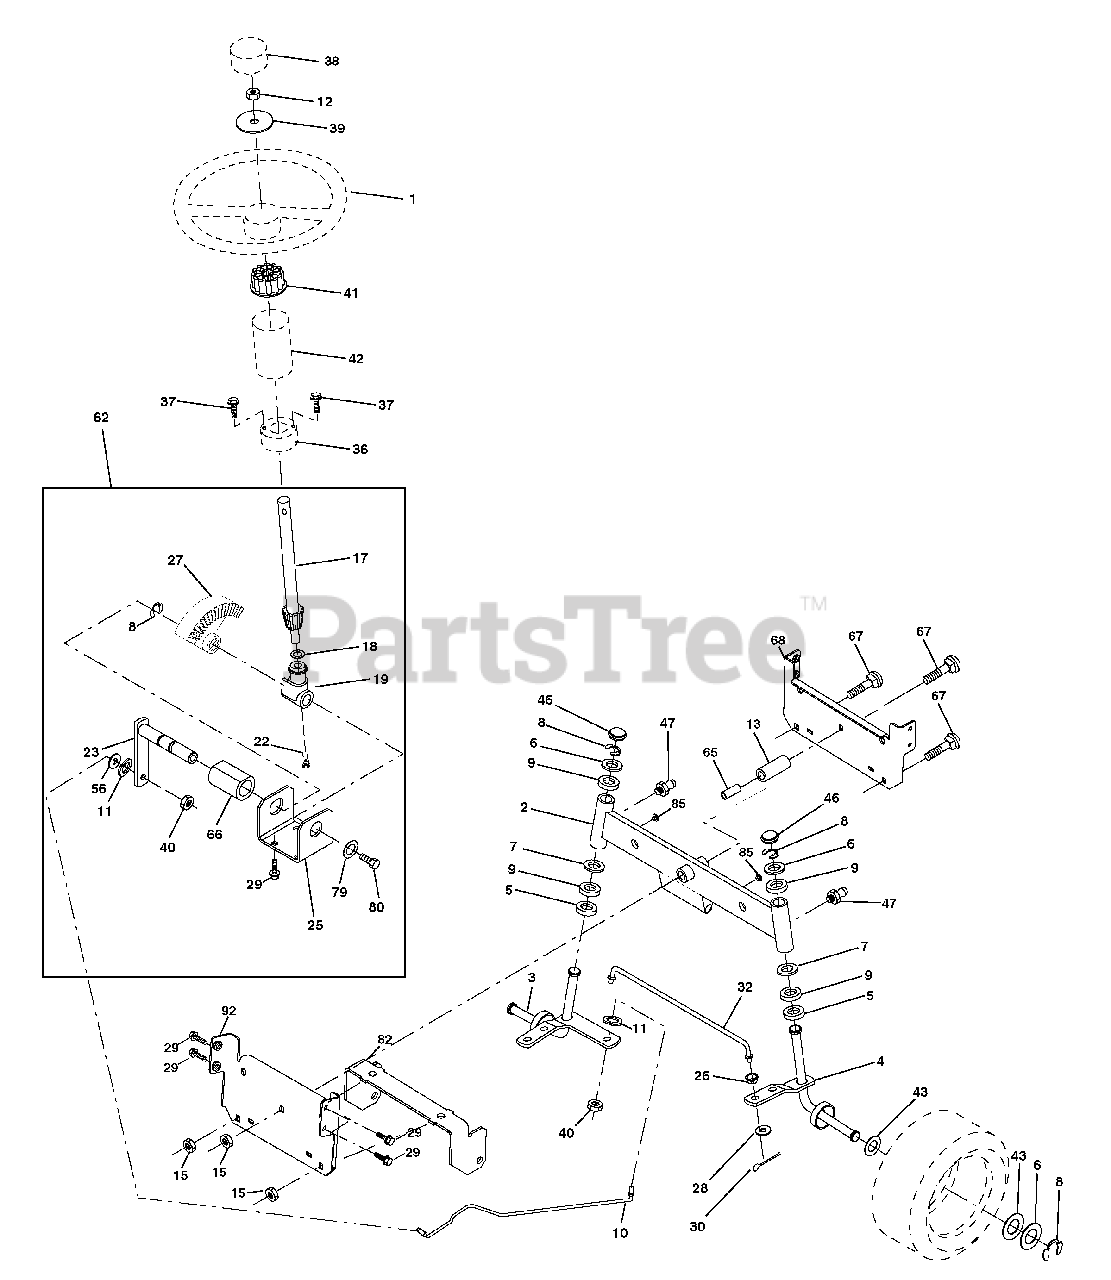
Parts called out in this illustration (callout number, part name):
1	Wheel Steering Auto Black
2	Axle Asm Front
3	Spindle Asm Lh
4	Spindle Asm Rh
5	Bearing Race Thrust Harden
6	Washer 25/32 X 1 5/8 X 16ga
7	Washer 27/32 X 1 1/4 X 16 Ga
8	Ring Klip #t5304-75
9	Bearing Col Strg Blk
10	Link Drag
11	Lockwasher
12	Nut Hex Jam Toplock 1/2-20 Unf
13	Spacer Bearing Axle Front
15	Nut Hex Flange Lock
17	Shaft Asm Strg
18	Washer Thrust 515x 750x 033
19	Support Shaft
22	Screw Hex WshHd Torx
23	Shaft Asm Pittman
25	Bracket Steering
26	Bushing Rod Tie Blk Lt
27	Gear Sector
28	Washer 13/32 X 7/8 X 16ga
29	Screw 3/8-16x3/4
30	Pin
32	Rod Tie Wire Form 19 75 Mech
36	Bushing Strg
37	Screw TT #10-32 x 5 x 3/8 Flange
38	Insert Cap Strg
39	Washer .53 x 2.25 x .160 Zinc
40	Locknut Center
41	Adaptor Wheel Strg 640/ 635id
42	Boot Dash Steering
43	Washer 25/32 X 1 1/4 X 16 Ga
46	Cap Spindle Fr Top Blk
47	Fitting Grease
56	Washer 13/32 x 3/4 x 10 Ga.
62	Kit Steering Assembly Service
65	Spacer Axle
66	Bearing Arm Pittman
67	Bolt Rdhd Sq 3/8-16 Unc x 2-1/4
68	Brace Axle Front
79	Washer 13/32 x 1-1/4 x 12 Ga.
80	Bolt Hex Nylon 3/8-16 x 3/4
82	Bracket Susp Chassis Front
85	Fastner Christmas Tree
92	Axle Rear 16" Tires GTV
